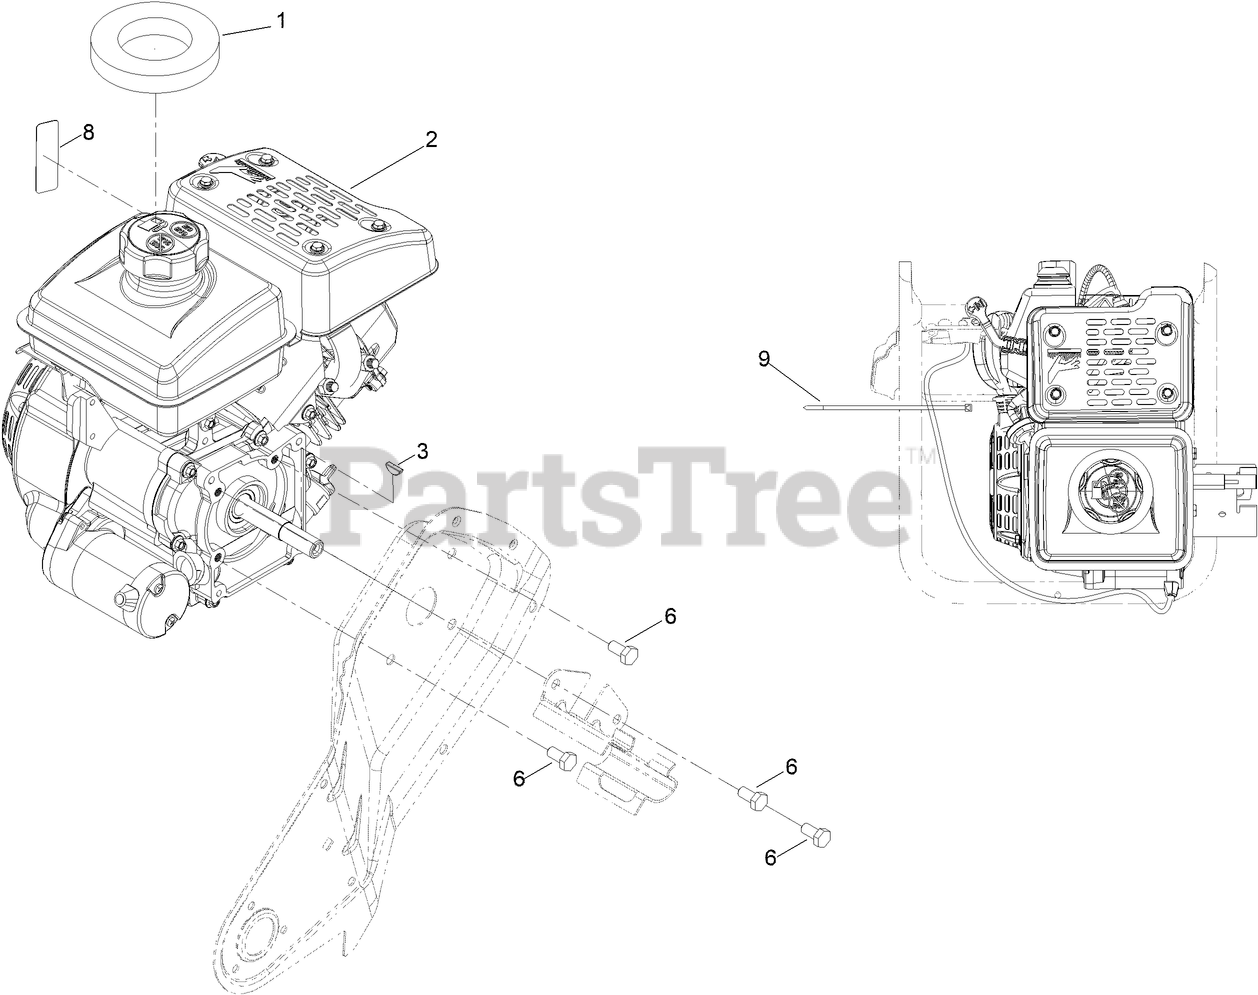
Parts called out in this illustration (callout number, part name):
1	SEAL-TANK
2	ENGINE-LC156FDS
3	KEY-WOODRUFF
6	BOLT
8	DECAL-CONTROLS, ENGINE
9	TIE-CABLE
